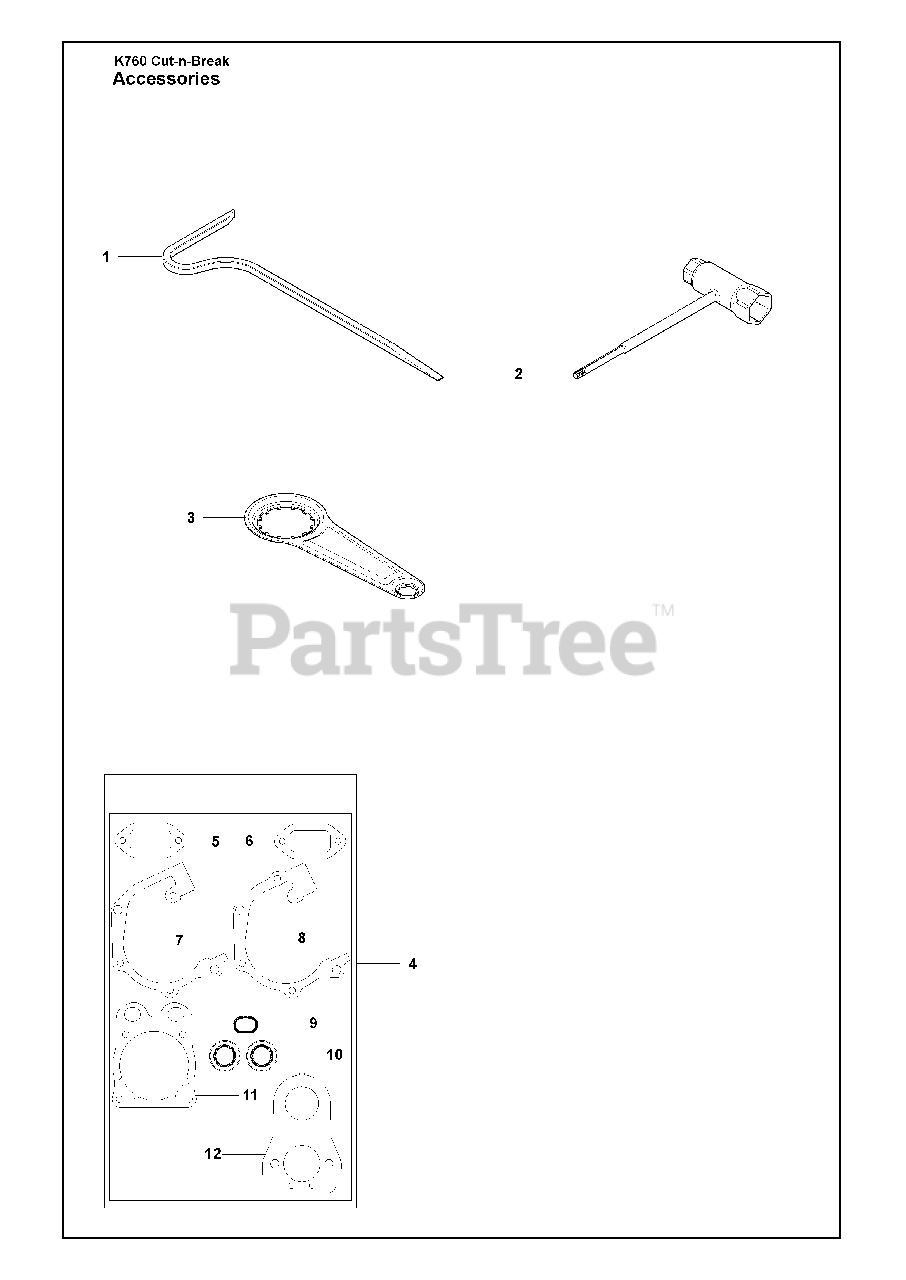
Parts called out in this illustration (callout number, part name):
1	Tool
2	Combination Tool
4	Gasket Kit
6	Gasket Muffler
7	Gasket Crankcase
8	Gasket Crankcase
10	Sealing Ring
11	Cylinder Base Gasket
12	Gasket Carburettor
